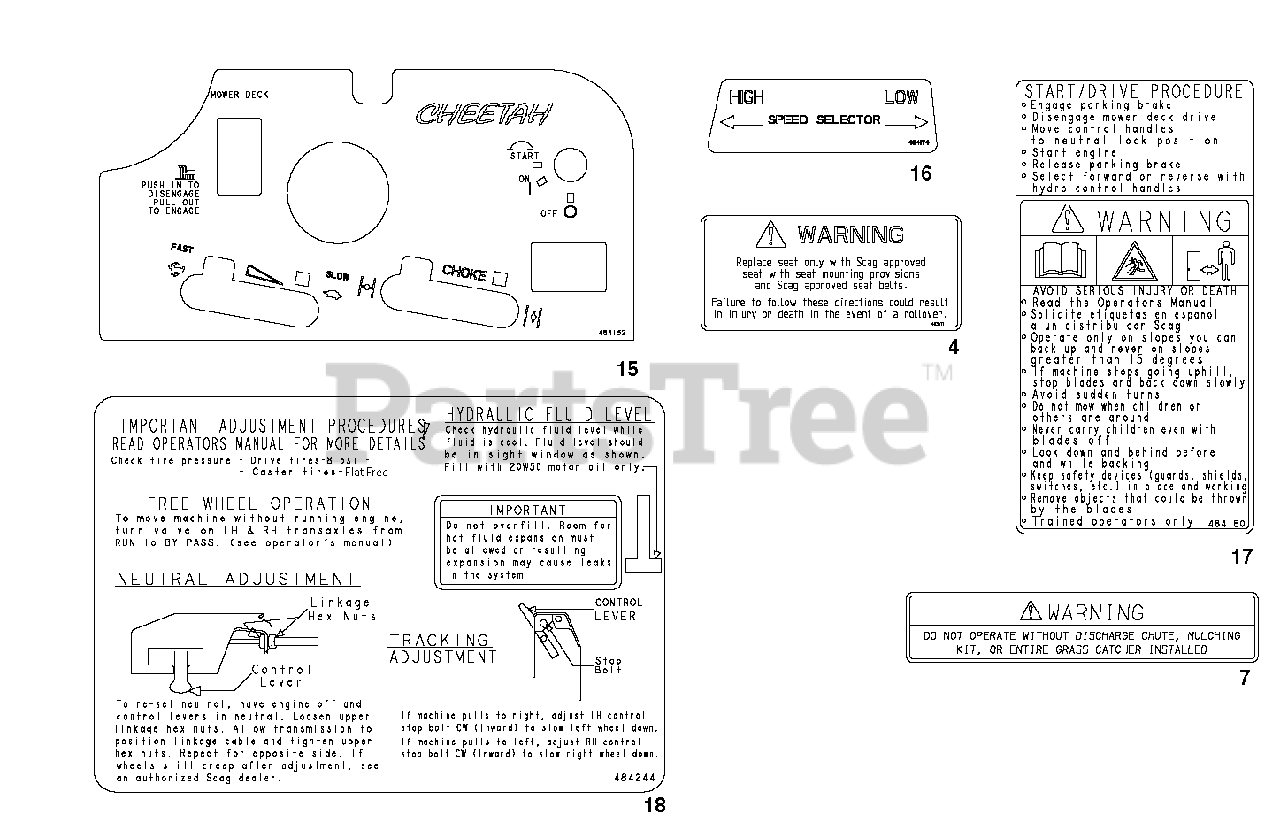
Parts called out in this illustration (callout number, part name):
4	Decal, Seat Replacement
7	Decal, Warning
15	Decal, Instrument Panel - SCZ
16	Decal, Speed Control
17	Decal, Start / Drive
18	Decal, Adjustments - SCZ
